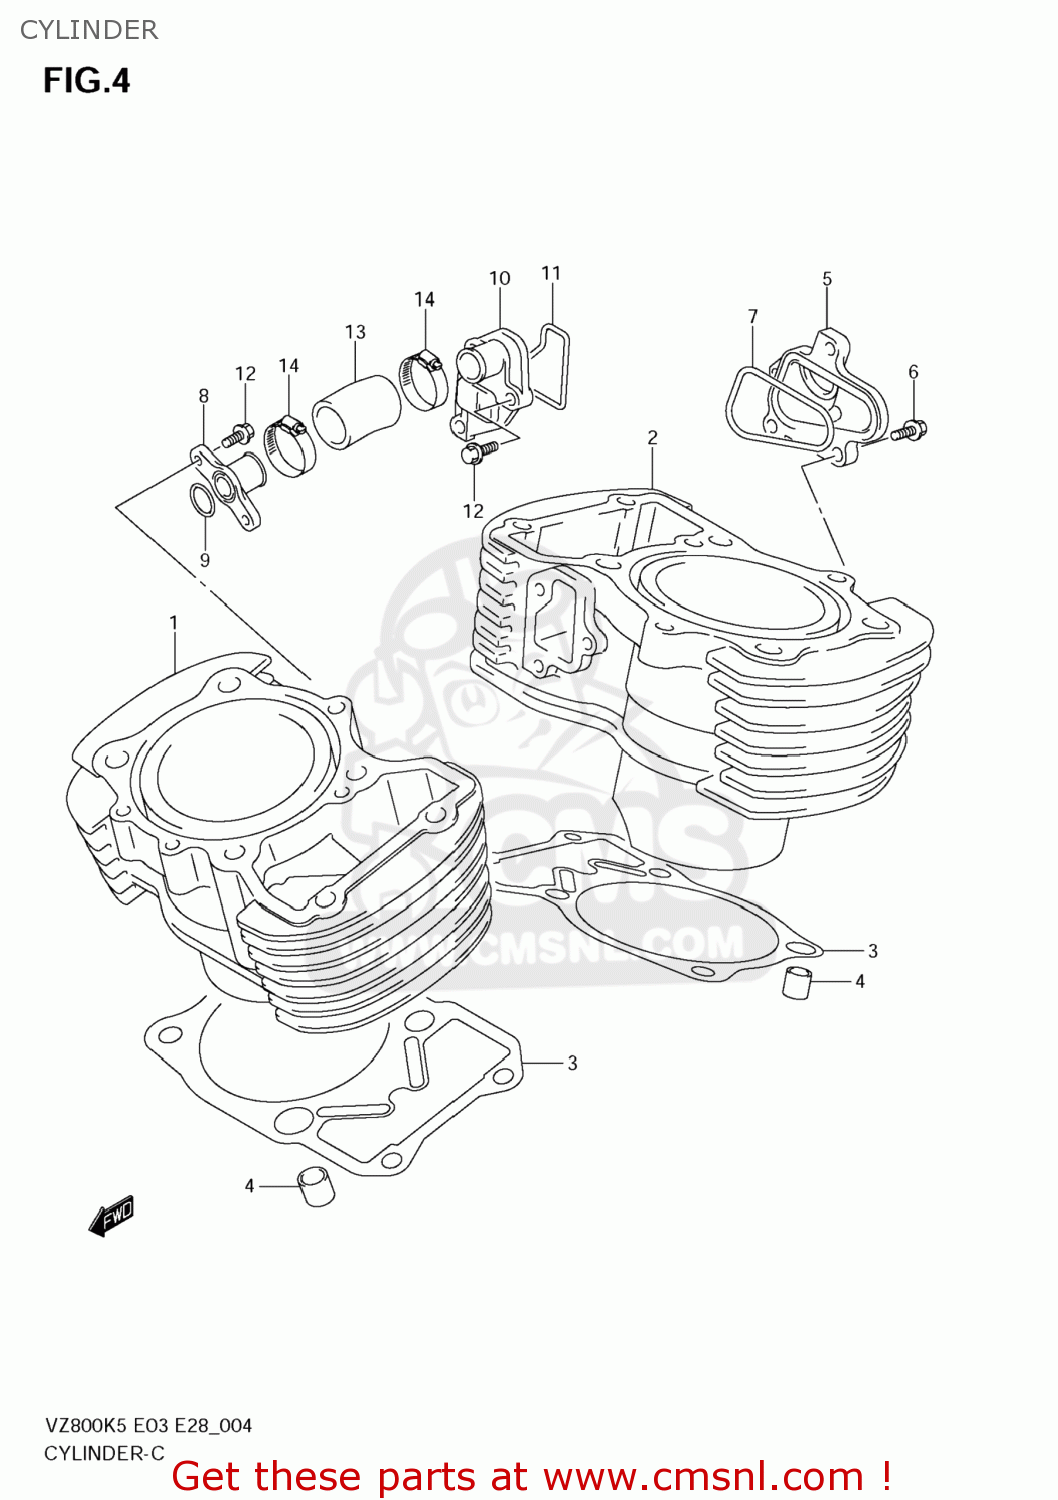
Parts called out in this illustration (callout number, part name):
1	CYLINDER,FR
2	CYLINDER,RR
3	GASKET,CYLINDER (NAS)
4	PIN
5	CONNECTOR,CYLINDER INLET PIPE
6	BOLT
7	O RING,INLET WATER CHAMBER
8	UNION,CYL INLET
9	O RING(D:2.4,ID:15.8)
10	UNION,CYL OUTLET
11	O RING,CYL OUTLET UNION
12	BOLT
13	HOSE,RADIATOR INLET
14	CLAMP
